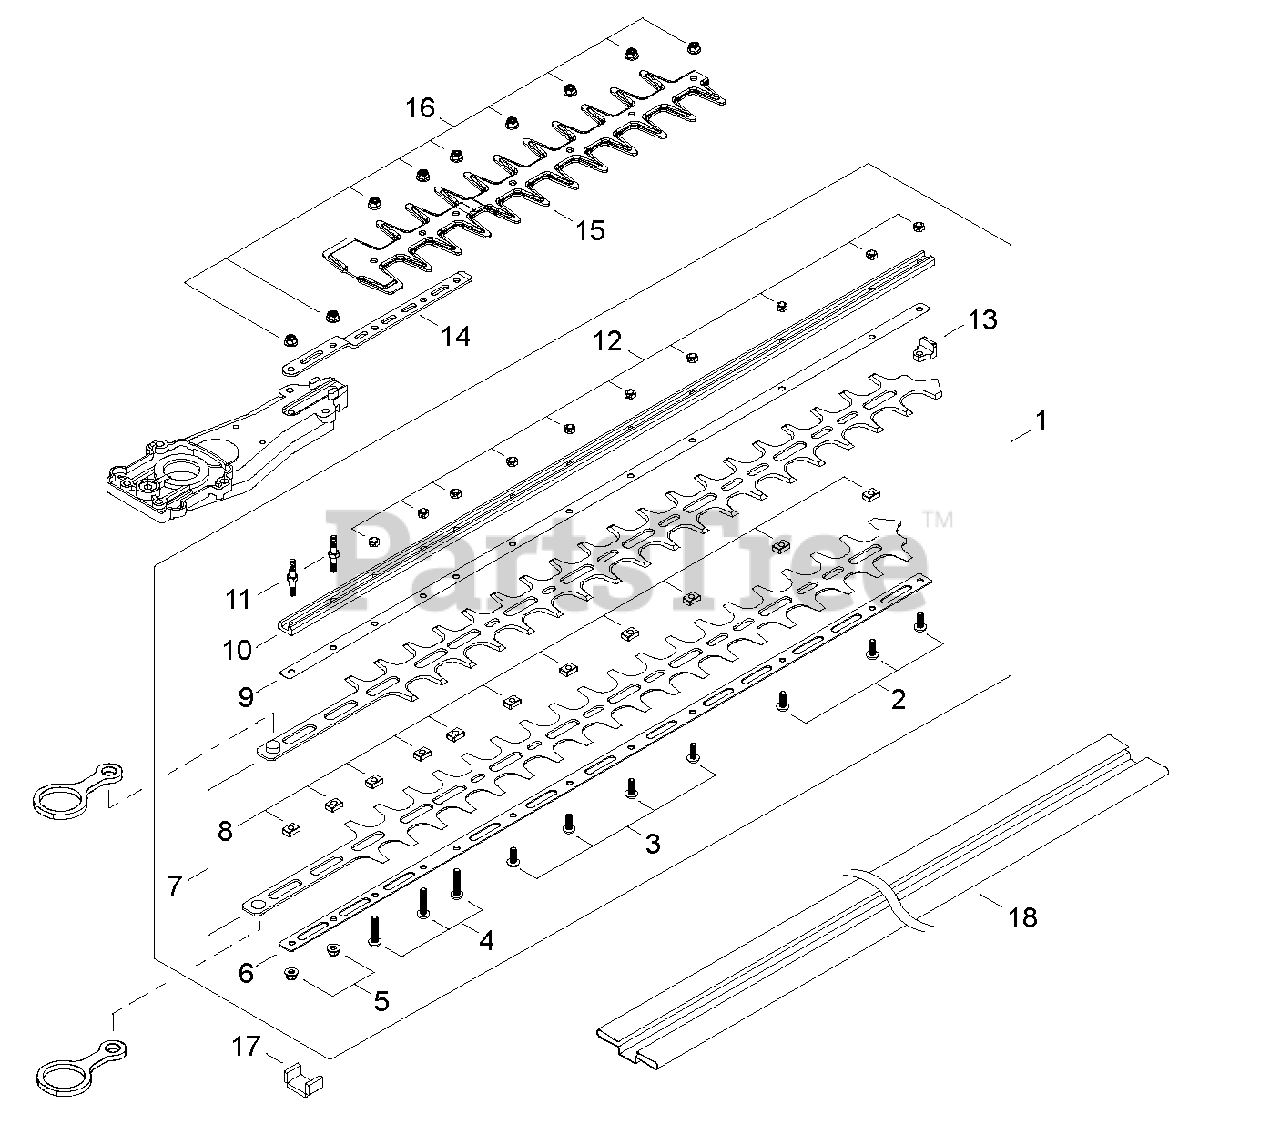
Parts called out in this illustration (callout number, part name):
1	CUTTER ASSY, 30"
2	BOLT M5×14
3	BOLT M5×22
4	BOLT M5×25
5	NUT M5
6	PLATE, LOWER
7	BLADE, 30"
8	SPACER
9	PLATE, UPPER
10	GUIDE BAR, 30"
11	STUD, MOUNTING M5
12	NUT, LOCK M5
13	BLOCK
14	BRACKET, CUTTER
15	GUARD, CUTTER BLADE
16	NUT M5
17	PACKING, FELT
18	SCABBARD 30"
